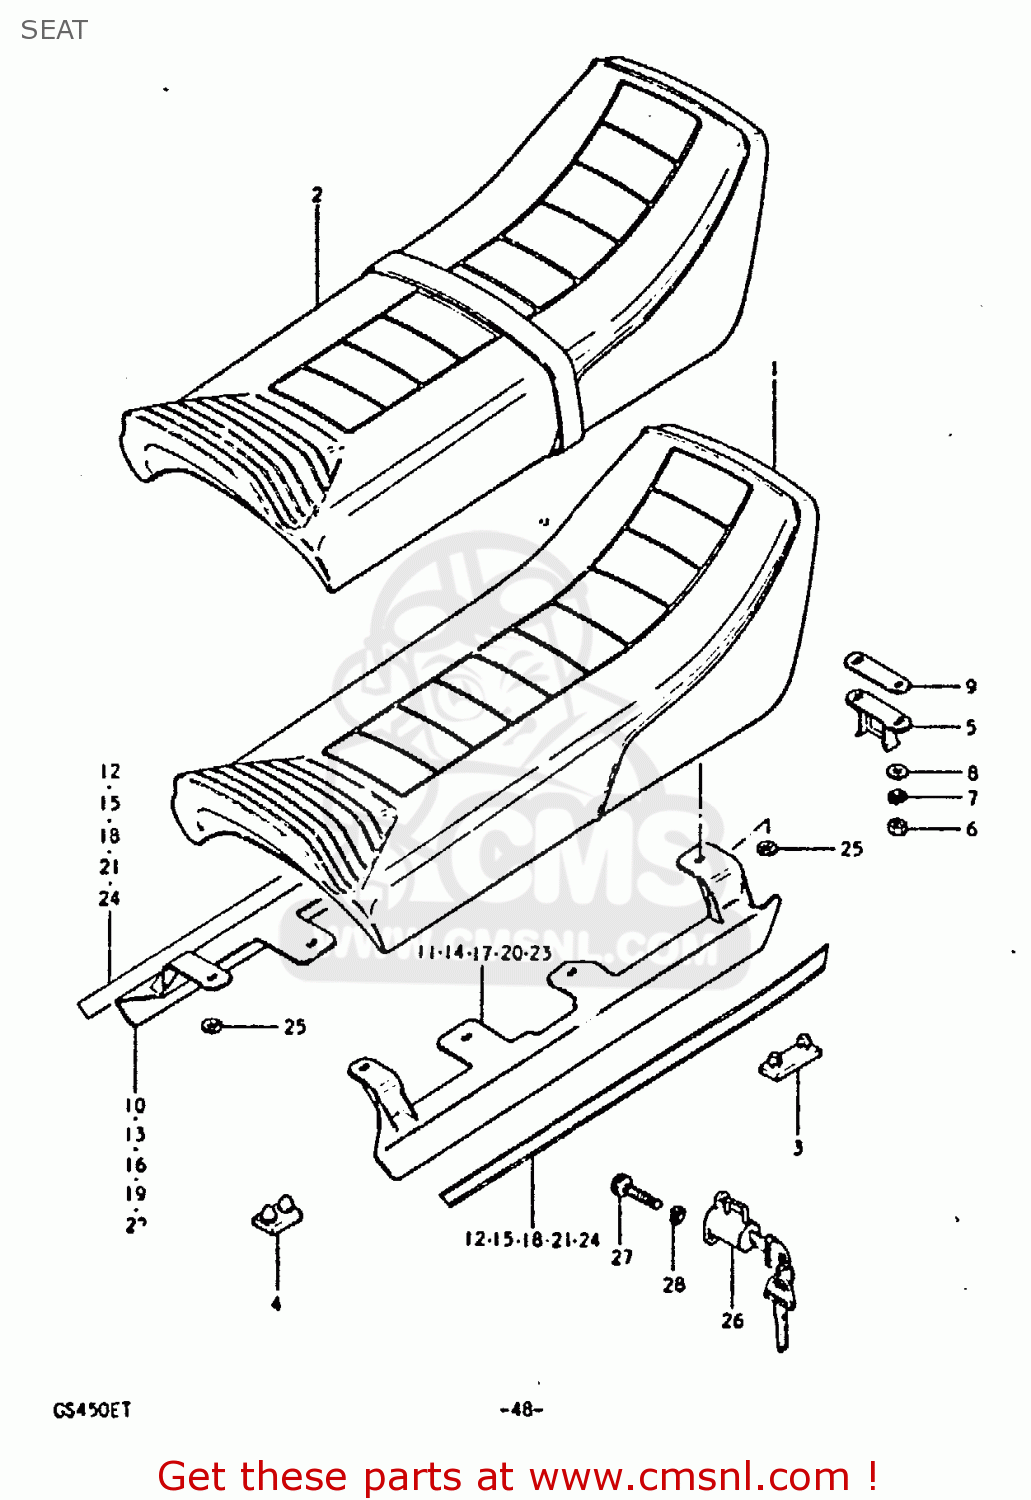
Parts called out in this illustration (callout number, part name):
1	SEAT ASSEMBLY
3	CUSHION
4	CUSHION
5	STRIKER,SEAT LOCK
6	SHIM,SEAT LOCK STRIKER
7	NUT 6MM
8	LOCK WASHER
9	WASHER
10	MOLDING,SEAT
11	MOLDING,SEAT
12	TAPE SET
13	MOLDING,SEAT
14	MOLDING,SEAT
15	TAPE SET
16	MOULDING, SEAT RH (BLUE)
17	MOULDING, SEAT LH (BLUE)
18	TAPE SET
19	MOLDING,SEAT
20	MOLDING,SEAT
21	TAPE SET
25	NUT
26	LOCK ASSEMBLY,HELMET
27	BOLT 6X11
28	LOCK WASHER
